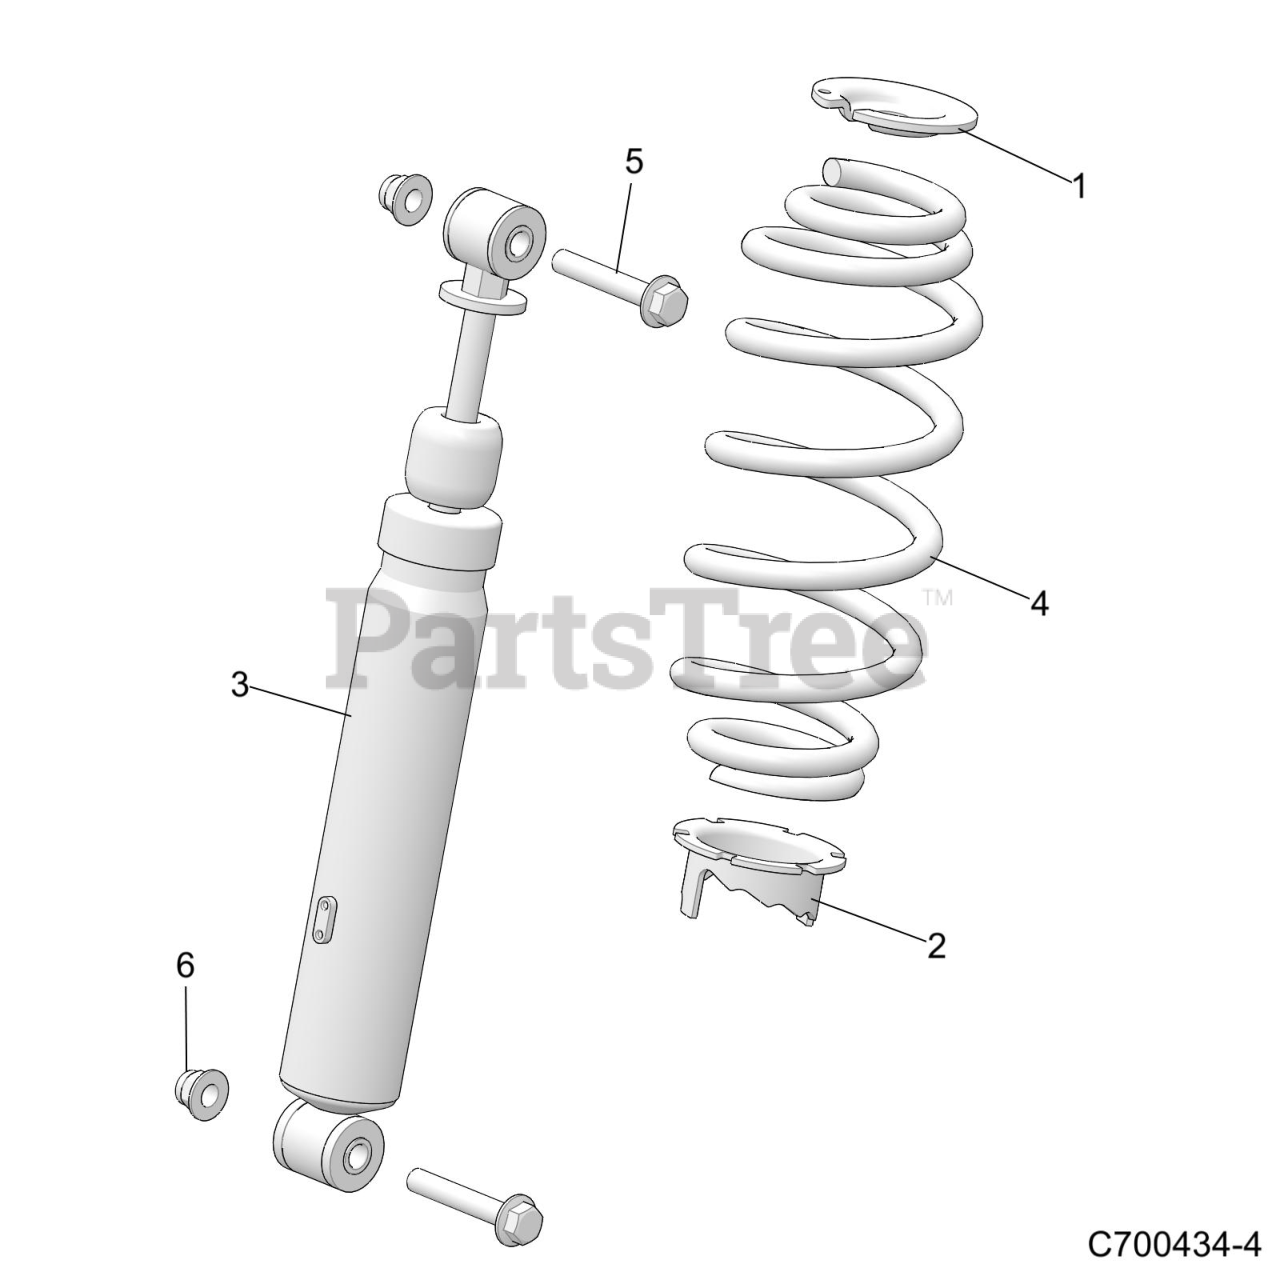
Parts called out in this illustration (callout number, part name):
1	RETAINER-SPRING,STEEL
2	CAM-ADJUSTER,ALUMN,2.30
3	SHOCK-FRONT
4	SPR-225-380#,12.1FL,2ID,M.BLK
5	SCR-HXFL-M10X1.25X60 10.9 ZOD
6	NUT-M10X1.25,FLG,NYLOC-OLIVE D
